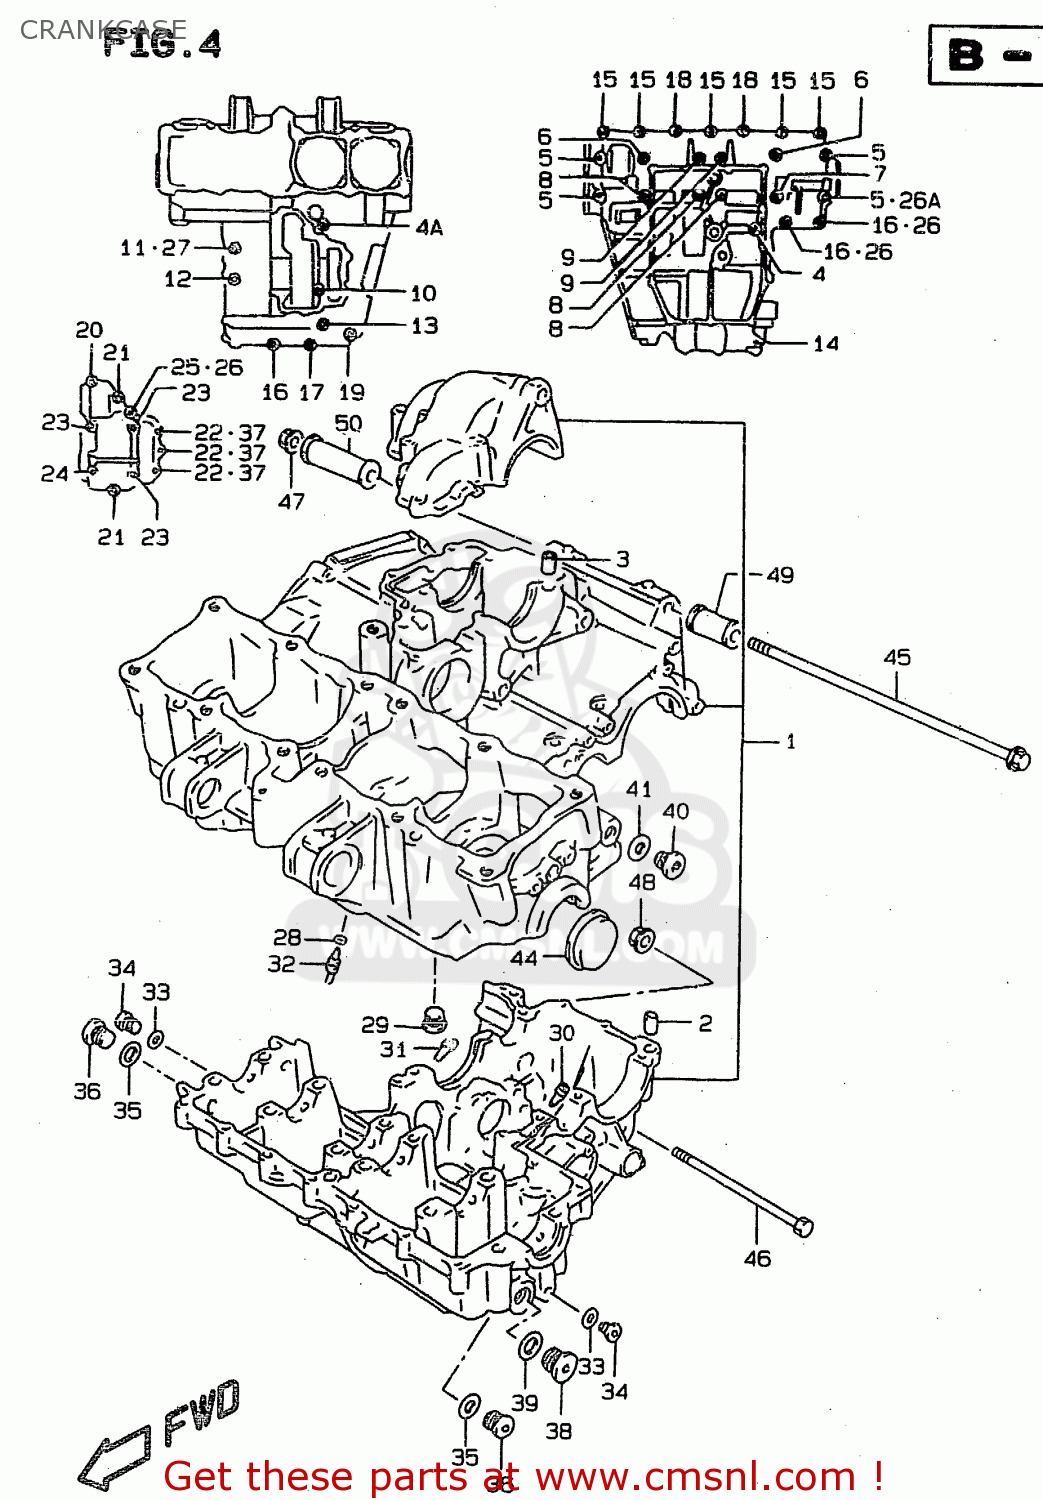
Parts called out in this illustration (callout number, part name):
1	CRANKCASE SET
2	PIN(10.4X13X22)
3	PIN
4	BOLT(6X105)
4A	BOLT(6X105)
5	BOLT 9X80
6	BOLT(9X95)
7	BOLT(9X105)
8	BOLT(9X115)
9	BOLT(9X60)
10	BOLT
11	BOLT
12	BOLT
13	BOLT
14	BOLT
15	BOLT
16	BOLT
17	BOLT
18	BOLT
19	BOLT
20	BOLT,CL.COVER
21	BOLT
22	BOLT
23	BOLT,CL.COVER
24	BOLT
25	BOLT(6X145)
26	GASKET(6.2X13X1.2) (NAS)
26A	GASKET(10.2X20X2).3 (NAS)
27	GASKET(8.2X14X1) (NAS)
28	O RING(D:1.2,ID:4)
29	PLUG,CRANKCASE,UPPER
30	JET
31	JET(140)
32	JET,OIL GALLERY
33	GASKET(10X14X3.6) (NAS)
34	PLUG(10X6.8)
35	GASKET(16X22X2) (NAS)
36	PLUG
37	GASKET(5.8X11X1.2) (NAS)
38	PLUG(22X11)
39	GASKET(22X27X2) (NAS)
40	PLUG
41	GASKET(13.8X18.8X4.8) (NAS)
42	BEARING,CRANK THRUST(GREEN)
43	BEARING,CRANK THRUST(RED)
44	PLUG
45	BOLT 10X280
46	BOLT(12X140)
47	NUT
48	NUT 12MM
49	SPACER,ENG MTG RR UPR,L(L45)
50	SPACER,ENGINE MOUNT
